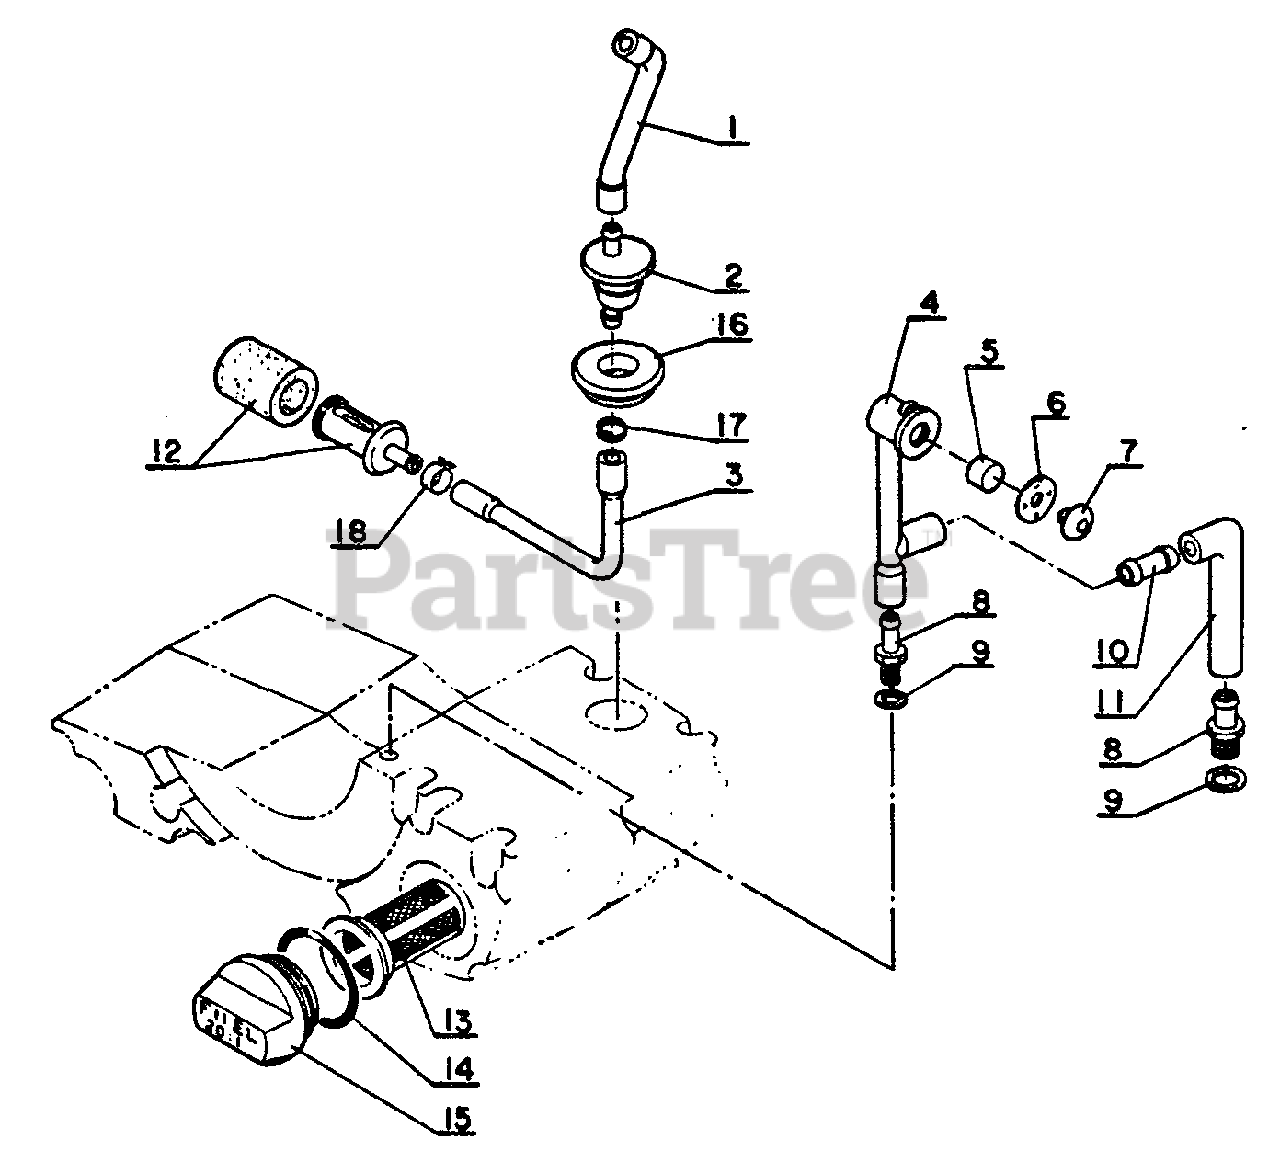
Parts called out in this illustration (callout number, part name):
1	PIPE - FUEL - OUTER
2	CONNECTOR, PIPE
3	PIPE, FUEL - INNER
4	PIPE - AIR
6	HOLDER, VENT
8	NIPPLE
9	O-RING
10	CONNECTOR
11	CONNECTOR
12	FILTER, FUEL
13	STRAINER
14	O-RING - 29
15	CAP
17	RETAINER, PIPE
18	CLIP
